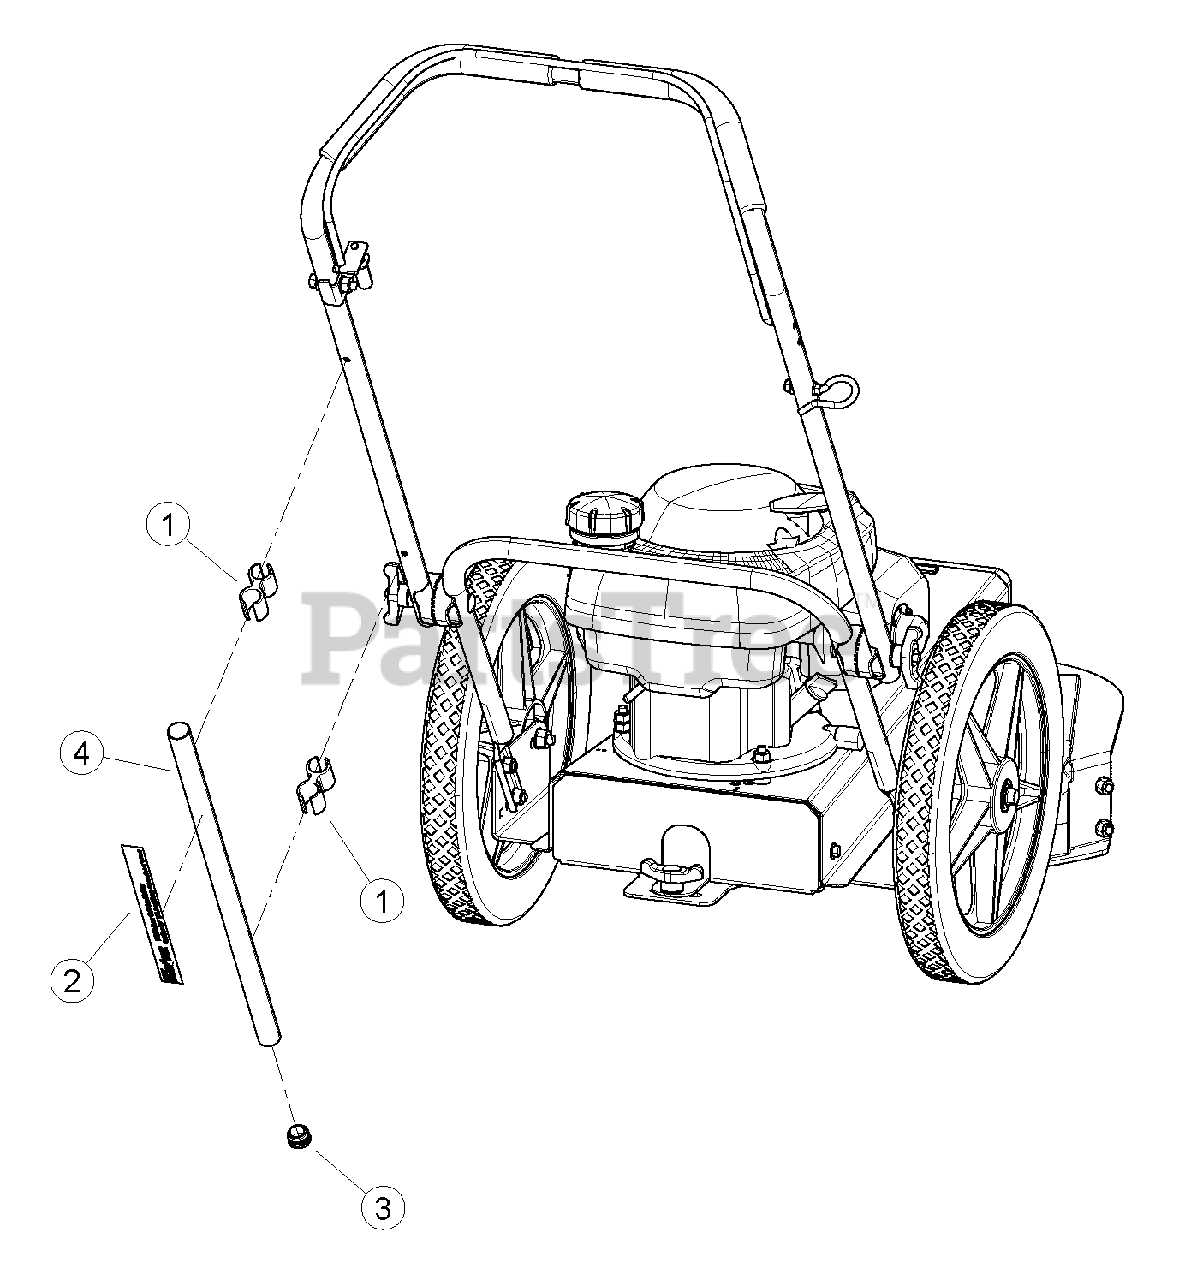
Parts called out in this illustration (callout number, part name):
1	CLIP, LINE TUBE
2	DECAL, TRIMMER LINE HOLDER
3	PLUG, LINE HOLDER TUBE
4	TUBE, TRIMMER LINE HOLDER
